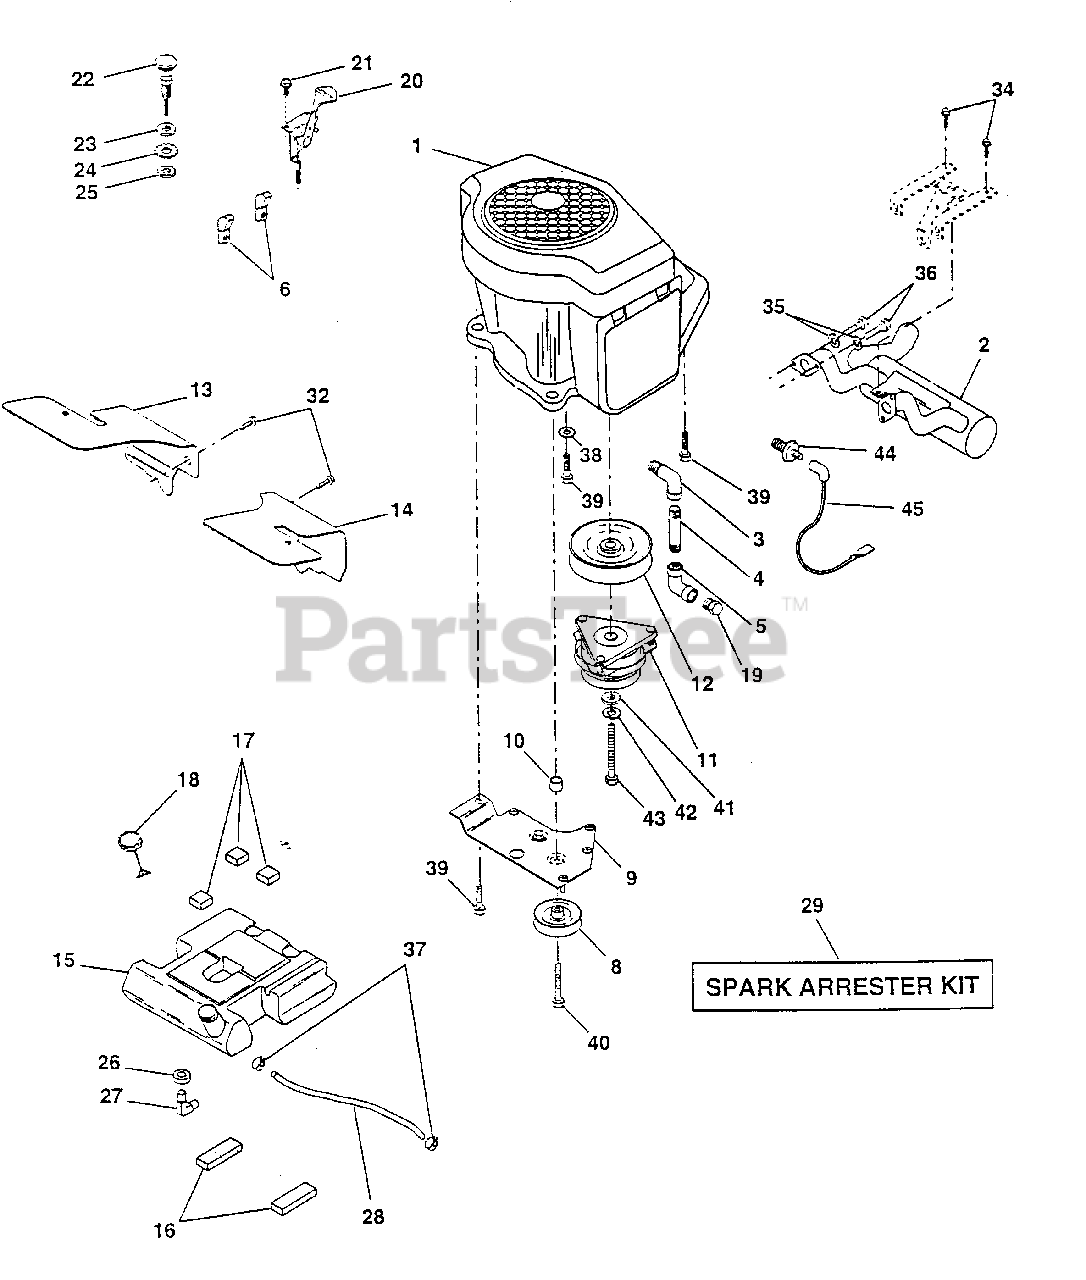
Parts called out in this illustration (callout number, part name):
2	Muffler Asm Kohler VGT (Inc. Key No. 34) (AYP part number)
3	Elbow Street 3/8 NPT (AYP part number)
4	Nipple Pipe 3/8NPT X 3 - 1/2 (AYP part number)
5	Elbow STD 90 Degree 3/8 - 18 NPT (AYP part number)
6	Clamp Tube Double Engine (AYP part number)
8	Pulley V-Idler (AYP part number)
9	Stop Keeper Asm VGT (AYP part number)
10	Bushing (AYP part number)
11	Clutch Electric (AYP part number)
12	Pulley Engine VGT Elect Clutch (AYP part number)
13	Baffle Air LH Koh VGT (AYP part number)
14	Baffle Air RH Koh VGT (AYP part number)
15	Tank Fuel W/Sym Vented (AYP part number)
16	Pad Spacer (AYP part number)
17	Pad Spacer (AYP part number)
18	Cap Asm Fuel W/Sym Vented (AYP part number)
19	Plug Oil Drain (Order From Engine Manufacturer) (AYP part number)
20	Control Throttle (AYP part number)
21	Screw Hex Thd Cut 1/4 - 20 X 5/8 (AYP part number)
22	Control Choke (AYP part number)
23	Washer 13/32 X 13/16 x 16 Ga (AYP part number)
24	Washer Ext Tooth 3/8 (AYP part number)
25	Nut Fin Hex 3/8 - 24 UNF (AYP part number)
26	Bushing (AYP part number)
27	Stem Tank Fuel (AYP part number)
28	Fuel Line (AYP part number)
29	Spark Arrester Kit (AYP part number)
32	Screw Thdrol 5/16 - 18 X 1/2 (AYP part number)
34	Screw Thd Cut 1.4 - 20 x 1/2 (AYP part number)
35	Washer Lock 5/16 (AYP part number)
36	Screw Hex 5/16 - 16 UNC X 3/4 (AYP part number)
37	Clamp Hose (AYP part number)
38	Lockwasher Ext Tooth 3/8 (AYP part number)
39	Screw Thdrol 3/8 - 16 X 1 - 1/2 TT (AYP part number)
40	Screw Thdrol 3/8 - 16 X 3 - 1/4 (AYP part number)
41	Washer 1-1/2 OD X 15/32 ID X .250 (AYP part number)
42	Washer Lock 7/16 (AYP part number)
43	Bolt Hex 7/16-20 X 4-1/4 Ga 5 (AYP part number)
44	Switch Oil Sentry Kohler (AYP part number)
45	Wire Lead Sentry Kohler (AYP part number)
